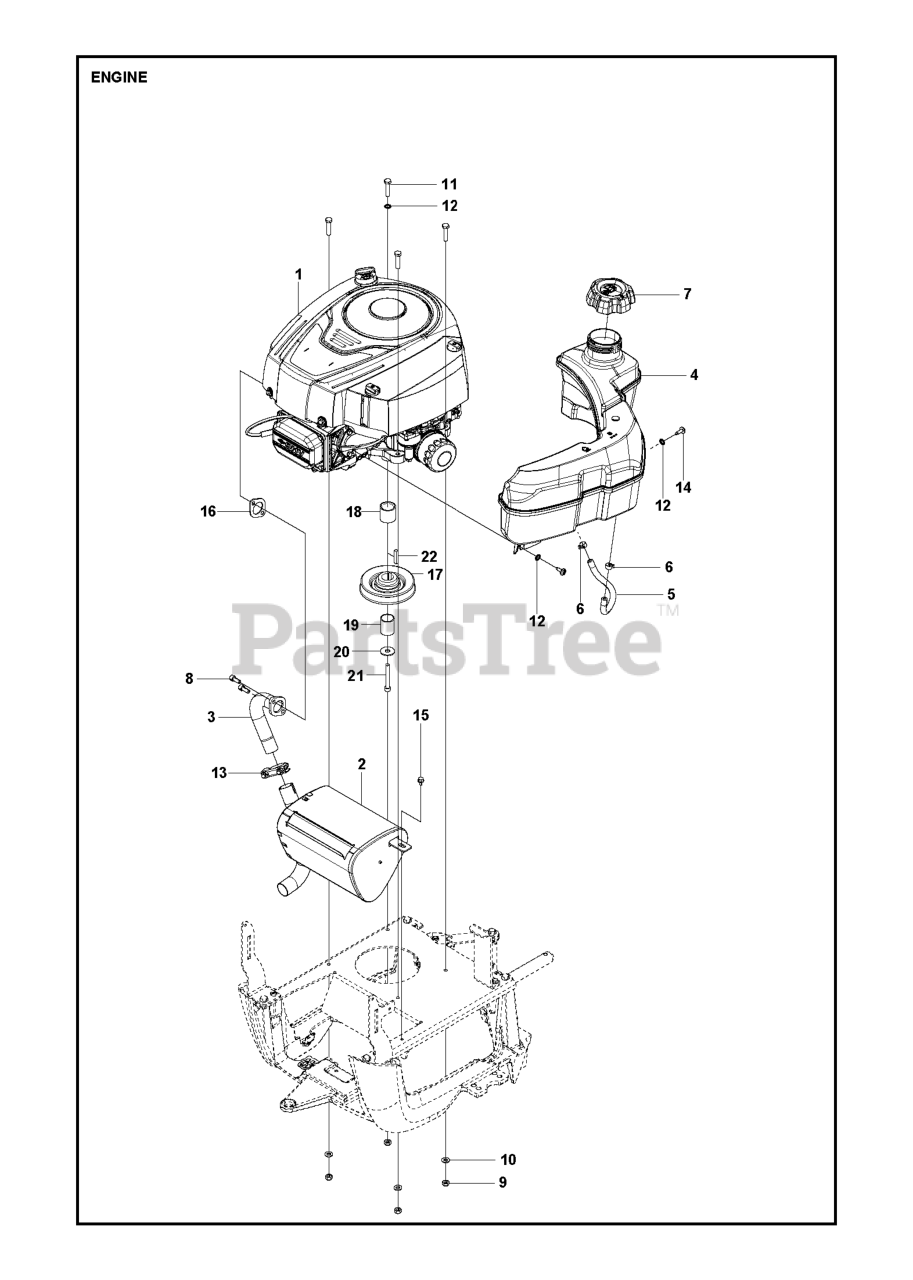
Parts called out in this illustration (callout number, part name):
2	MUFFLER ASSY
7	CAP.ASSY.FUEL.3".N-EPA.GRY.498
9	LOCKNUT M8
10	WASHER BRB 8.4X17
13	CLAMP ASSY EXHAUST
18	SPACING SLEEVE
